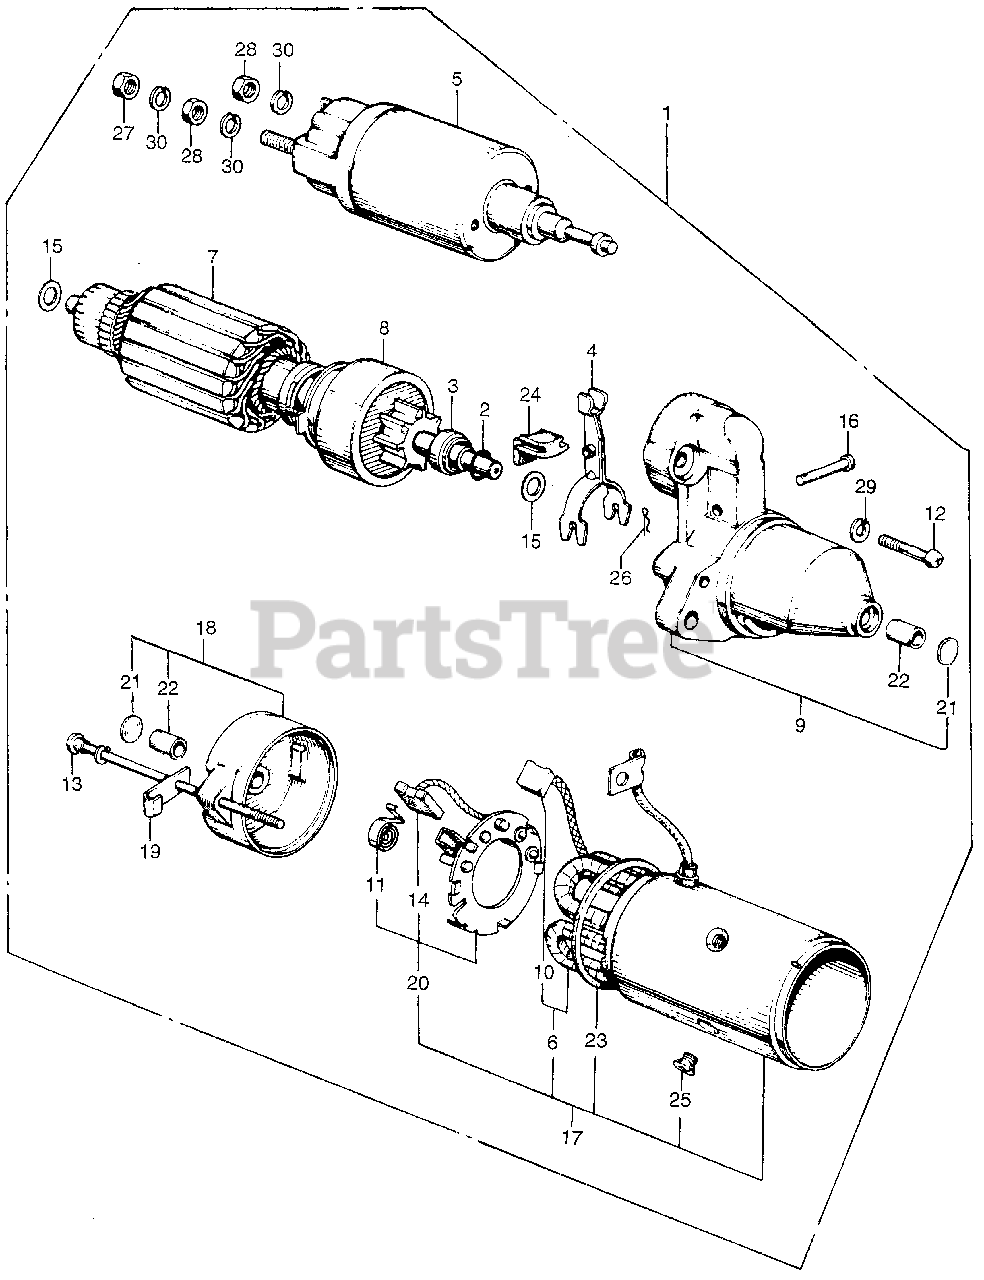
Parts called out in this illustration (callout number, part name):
1	MOTOR ASSY., STARTER (NOT AVAILABLE)
2	RING, SNAP (NOT AVAILABLE)
3	COLLAR, CLUTCH STOP
4	LEVER, PINION (NOT AVAILABLE)
5	SWITCH, MAGNET
6	COIL, FIELD (NOT AVAILABLE)
7	ARMATURE (NOT AVAILABLE)
8	CLUTCH, OVERRUNNING
9	HOUSING, DRIVE SIDE
10	BRUSH (NOT AVAILABLE)
11	SPRING, BRUSH
12	SCREW, MAGNETIC SWITCH SETTING
13	BOLT, THROUGH
14	BRUSH
16	BOLT, DRIVE LEVER SET
18	COVER, RR.
20	PLATE, BRUSH HOLDER (NOT AVAILABLE)
21	COVER, BEARING
22	BUSH, BEARING
23	GASKET, RUBBER PLATE
24	PART, RUBBER
25	SCREW, POLE CORE
27	NUT, HEX. (8MM)
28	NUT, HEX. (8MM)
29	WASHER, SPRING (6MM)
30	WASHER, SPRING (8MM)
